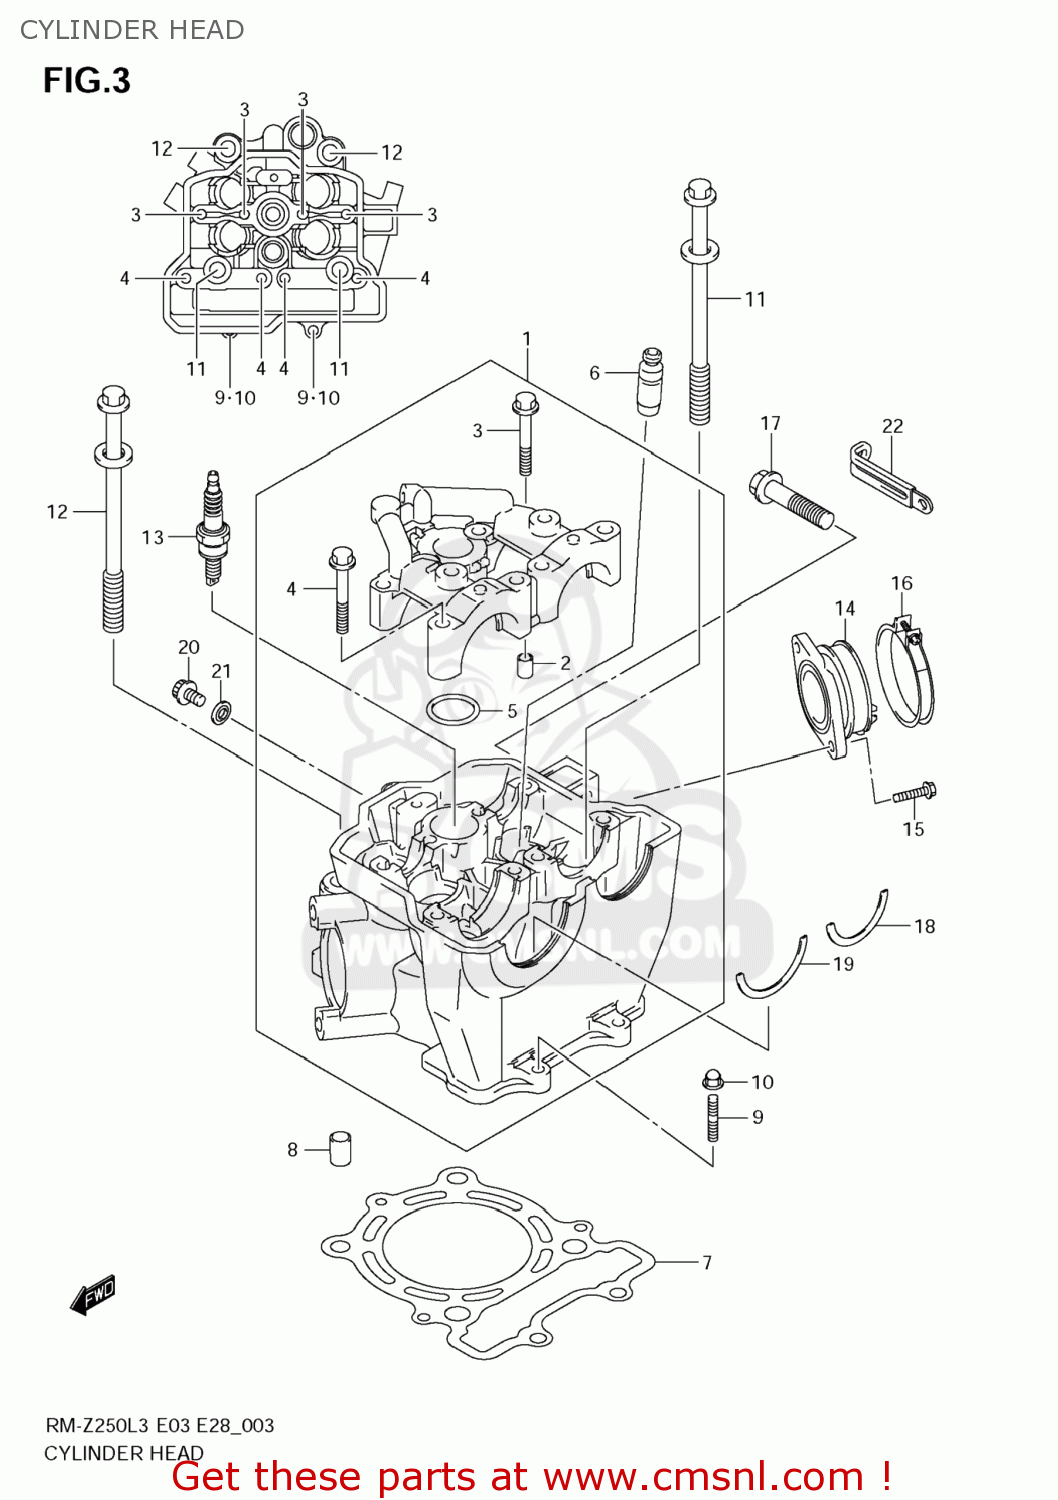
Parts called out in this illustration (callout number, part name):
1	HEAD ASSY,CYLINDER
2	PIN(6.2X8X11)
3	BOLT(6X40)
4	BOLT(6X45)
5	O RING(D:2.4,ID:25.7)
6	GUIDE,VALVE(OS:0.3)
7	GASKET,CYLINDER HEAD (NAS)
8	PIN
9	BOLT,STUD
10	NUT
11	BOLT,CYLINDER HEAD
12	BOLT,CYLINDER HEAD
13	PLUG,SPARK(CR8EIB-10)
14	PIPE ASSY,INTAKE
15	BOLT
16	CLAMP,INTAKE PIPE
17	BOLT(10X40)
18	C RING,CAMSHAFT
19	C RING,CAMSHAFT
20	BOLT
21	GASKET(5.8X13X1.2) (NAS)
22	CLAMP(L:45)
